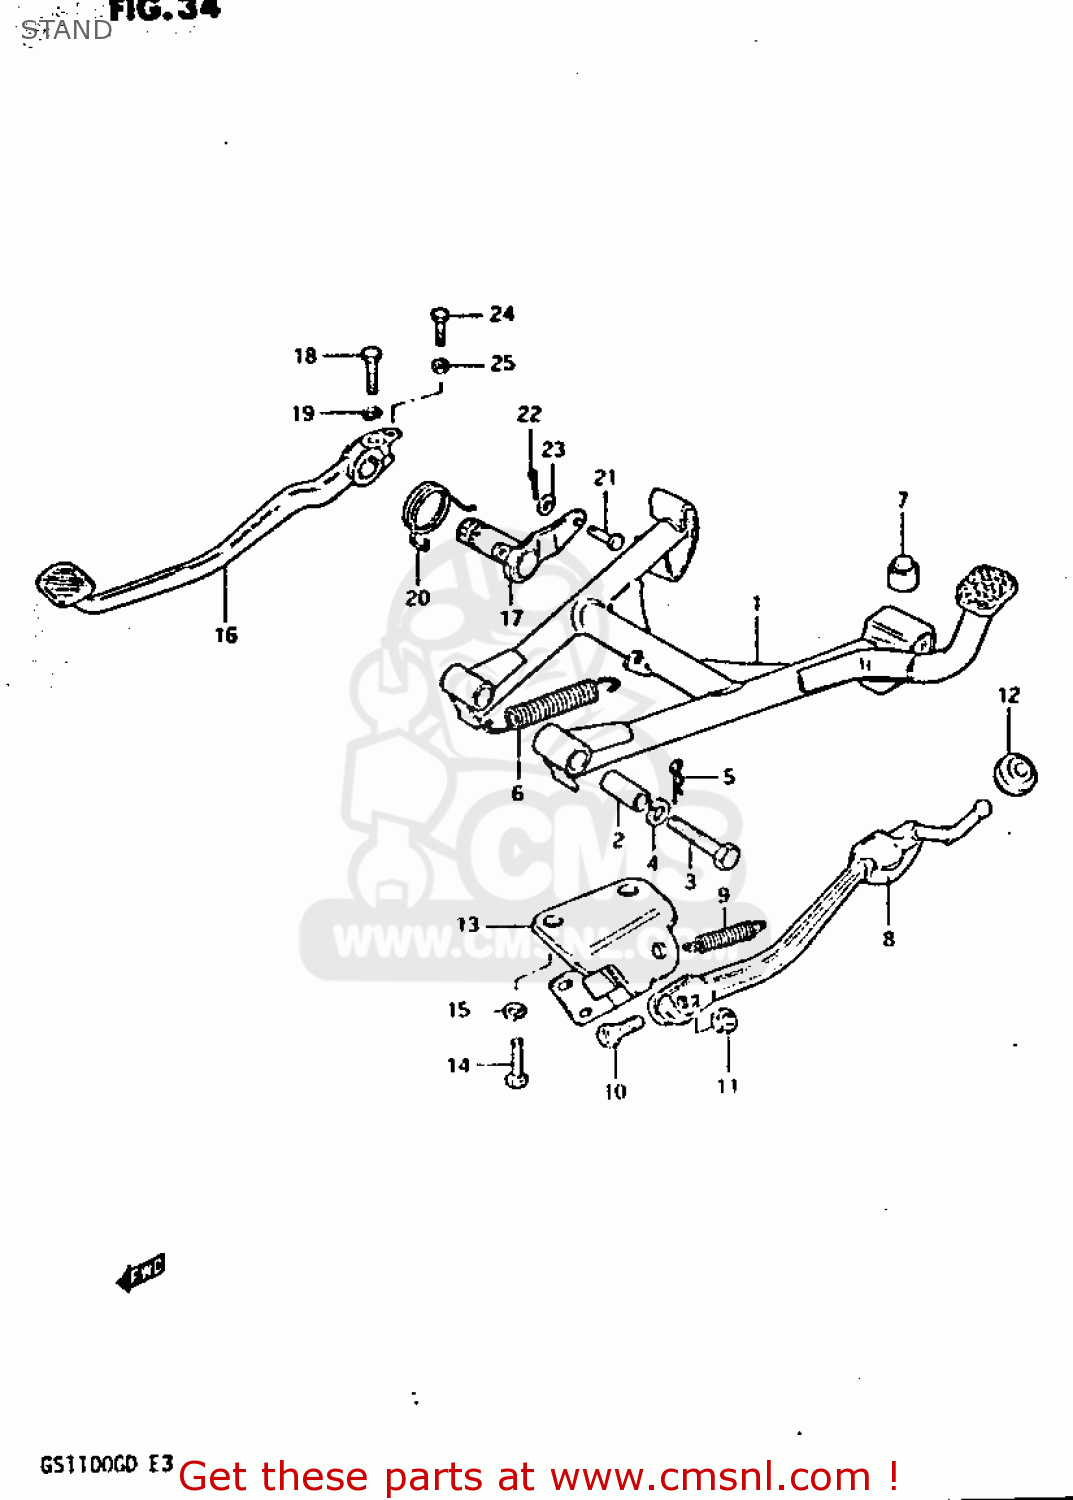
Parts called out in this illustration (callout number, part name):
1	STAND,CENTER
2	SPACER(10X16X38.8)
3	BOLT(10X65)
4	WASHER,LOCK,10
5	CLIP
6	SPRING
7	CUSHION
8	STAND,PROP
9	SPRING
10	BOLT(10X30)
11	NUT
12	CUSHION
13	BRACKET,SIDE STAND
14	BOLT
15	WASHER,LOCK,10
16	PEDAL,BRAKE
17	ARM,BRAKE PEDAL ROD
18	BOLT
19	LOCK WASHER
20	SPRING
21	PIN
22	PIN
23	WASHER
24	BOLT
25	NUT
